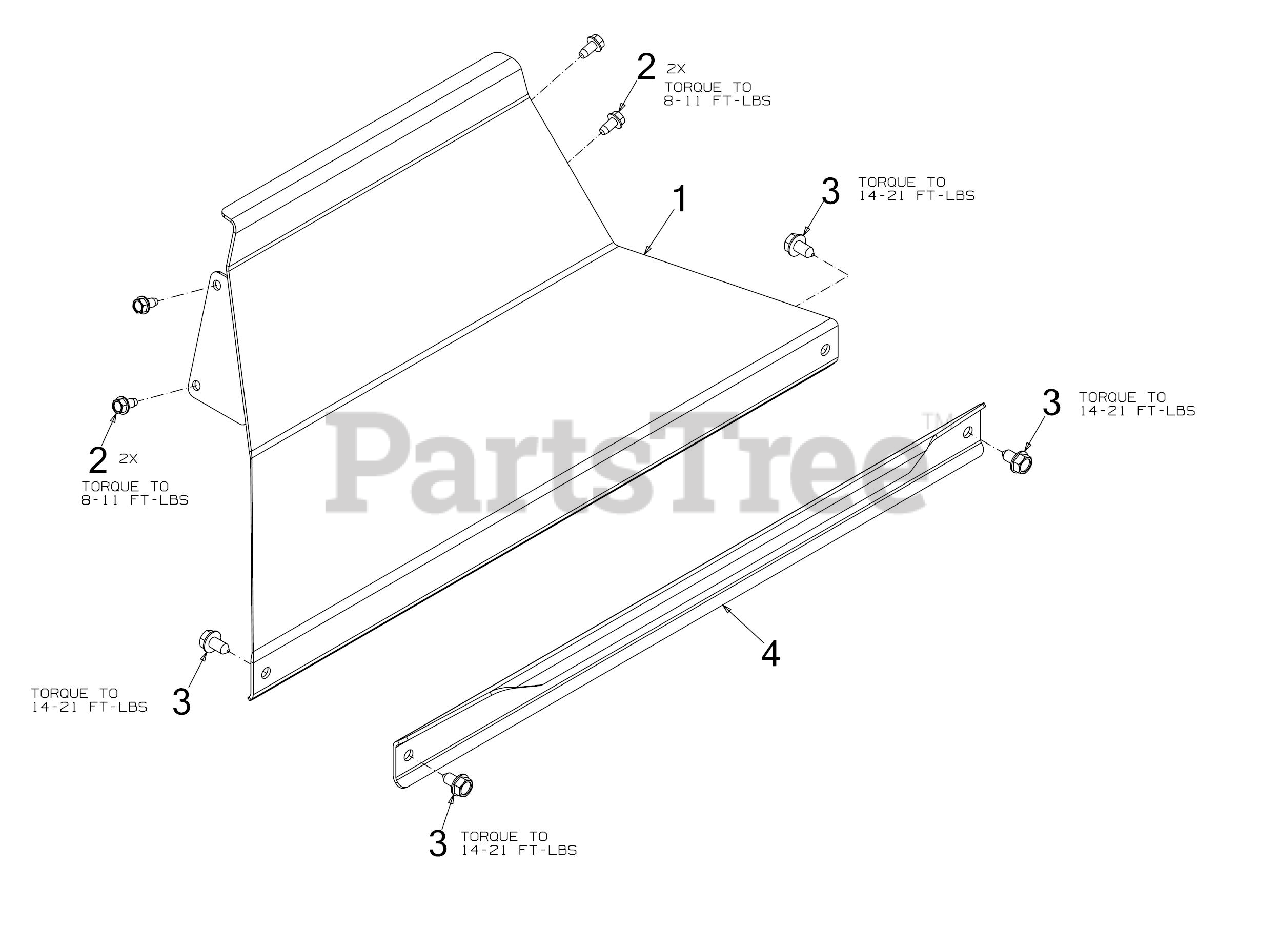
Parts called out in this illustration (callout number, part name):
1	SUPPORT ASSEMBLY
2	SCREW 1/4-20 X.500
3	SCREW 5/16-18 x .625
4	SUPPORT BRACKET
